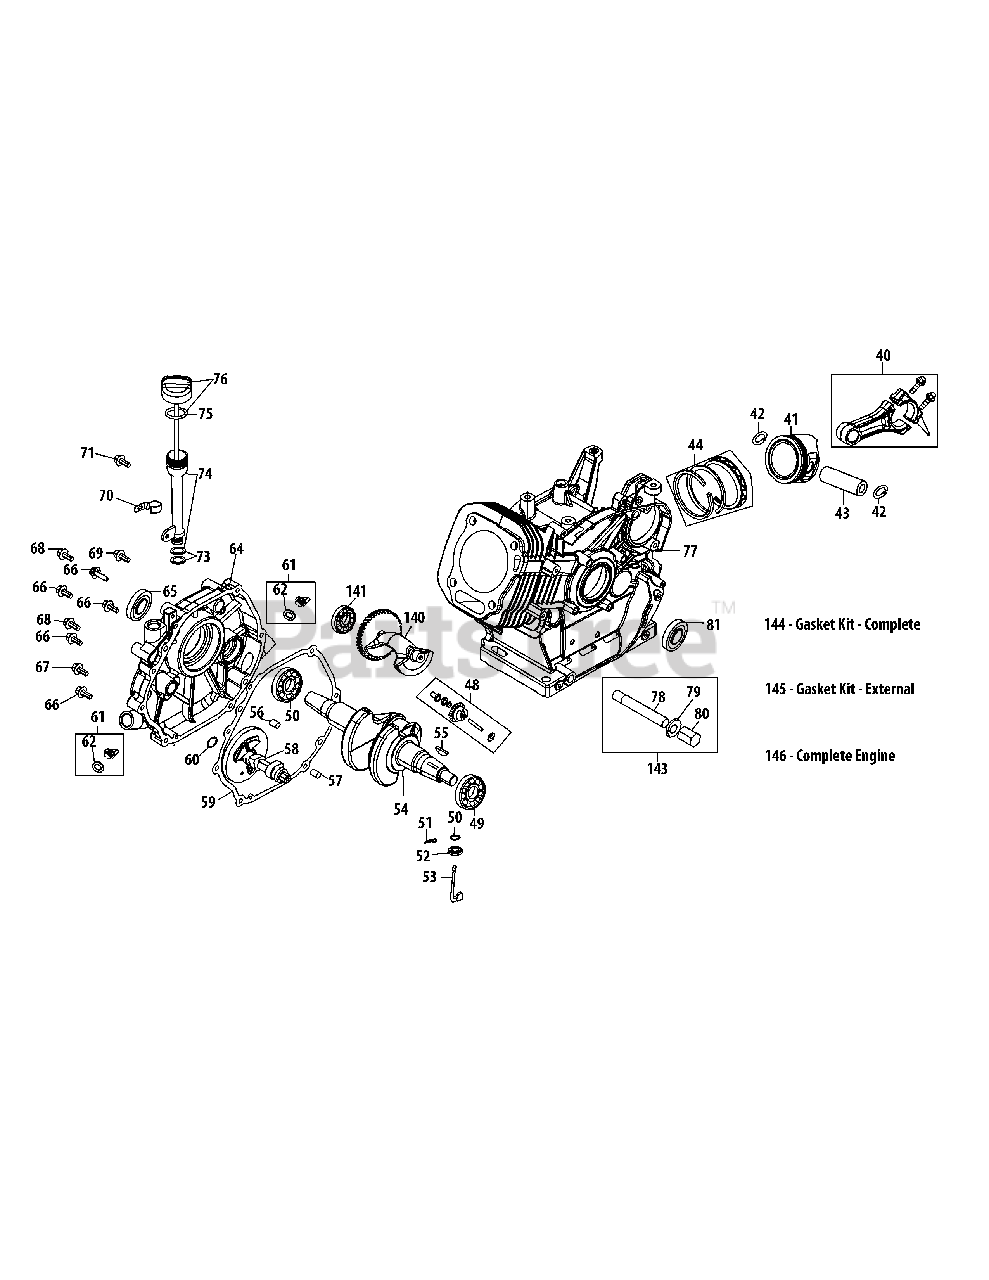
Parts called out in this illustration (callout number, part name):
40	Connecting Rod Assembly
41	Piston
42	Piston Pin Snap Ring
43	Piston Pin
44	Piston Ring Set
48	Governor Gear/Shaft Assembly
49	Radial Ball Bearing
50	Flat Washer
51	Governor Shaft Clip
52	Governor Seal
53	Governor Arm Shaft
54	Crankshaft Kit
55	Woodruff Key
56	Dowel Pin 9 X 12
57	Dowel Pin 7 X 14
58	Camshaft Assembly
59	Crankcase Cover Gasket
60	Washer
61	Oil Fill Plug Assembly
62	O-Ring
64	Crankcase Cover
64	Crankcase Cover Kit
65	Oil Seal
66	Bolt M8×38
67	Bolt M8×45
68	Bolt M8×35
69	Bolt M6×16
70	Oil Tube Support Bracket
71	Bolt M6×8
73	Oil Fill Tube O-Ring
74	Oil Fill Tube Assembly
75	Dipstick O-Ring
76	Dipstick Assembly
77	Crankcase Kit
77	Short Block Assembly
78	Oil Drain Pipe
79	Drain Pipe Washer 10X16X1.5
80	Oil Drain Plug Bolt
81	Oil Seal
140	Balance Gear Assembly
141	Bearing
143	Oil Drain Asm
144	Gasket Kit - Complete
145	Gasket Kit - External
146	Complete Engine
